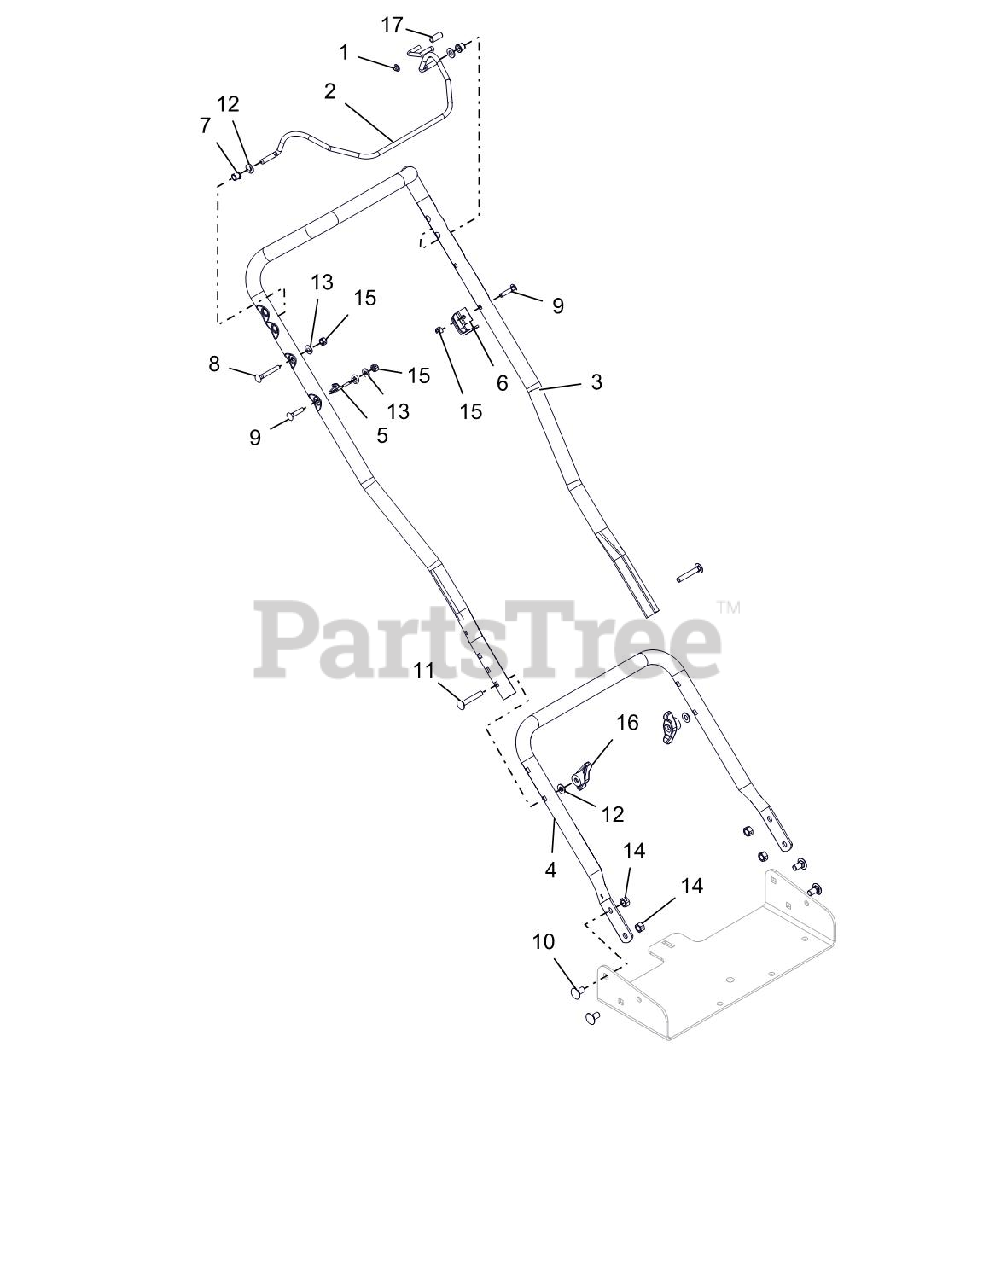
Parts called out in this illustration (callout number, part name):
1	PUSH NUT, .25
2	BAIL SS LF
3	HANDLEBAR - UPPER
4	HANDLEBAR - LOWER
5	GUIDE - PULLCORD
6	ANCHOR - CABLE
7	BSHG-FLG .325X.444X.440X.560
8	BLT-RDHDXLSQNK .25-20X2.0 G5YZ
9	BLT-RDHDXLSQNK.25-20X1.25 G5ZC
10	@BLT-RDHDSQNK .38-16X.75 G5YZ
11	BLT-RDHDSQNKFT .31-18X2.0 G5YZ
12	@WSHR-FL-STL.344X.688X.065YWZC
13	@WSHR-FL-STL.281X.62X.065 YWZC
14	@NUT-LK-CTR .38-16 YWZC
15	@NUT-LK-CTR .25-20 YWZC
16	KNOB,WING .31-18 UNC NYL/TALC
17	CAP, VINYL, .25 ID
